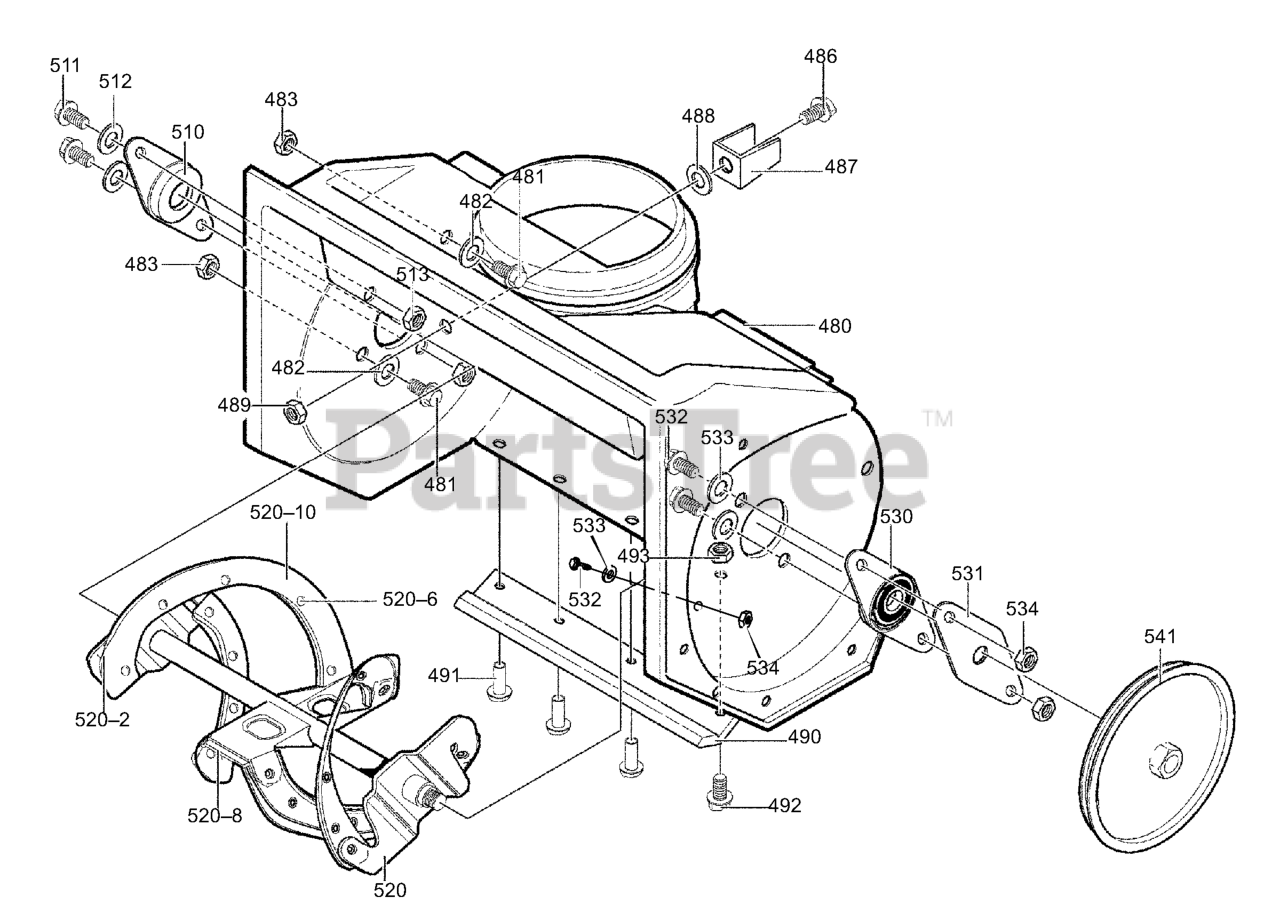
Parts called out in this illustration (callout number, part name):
480	HOUSING, ASSY
481	SCREW, 1/4-20X.75
482	WASHER, FLAT
483	NUT, 1/4-20
486	SCREW, 1/4-20X.63
487	BRACKET, STOP
488	WASHER, FLAT
489	NUT, 1/4-20 HEX NYLOCK
490	BLADE, SCRAPER
491	RIVET
492	SCREW, 1/4-20X.75
493	NUT, 1/4-20
510	BEARING, FLANGE
511	SCREW, 1/4-20X1.00
512	WASHER, FLAT
513	NUT, CNTRLK 1/4-20
520	AUGER, ASSY
520-2	BLADE, AUGER
520-6	RIVET
520-8	BLADE, CENTER
520-10	AUGER & BLADE SUPPORT
530	BEARING & PLATE ASSY
531	PLATE, RETAINER
532	SCREW, 1/4-20X.63
533	WASHER, FLAT
534	NUT, 1/4-20
